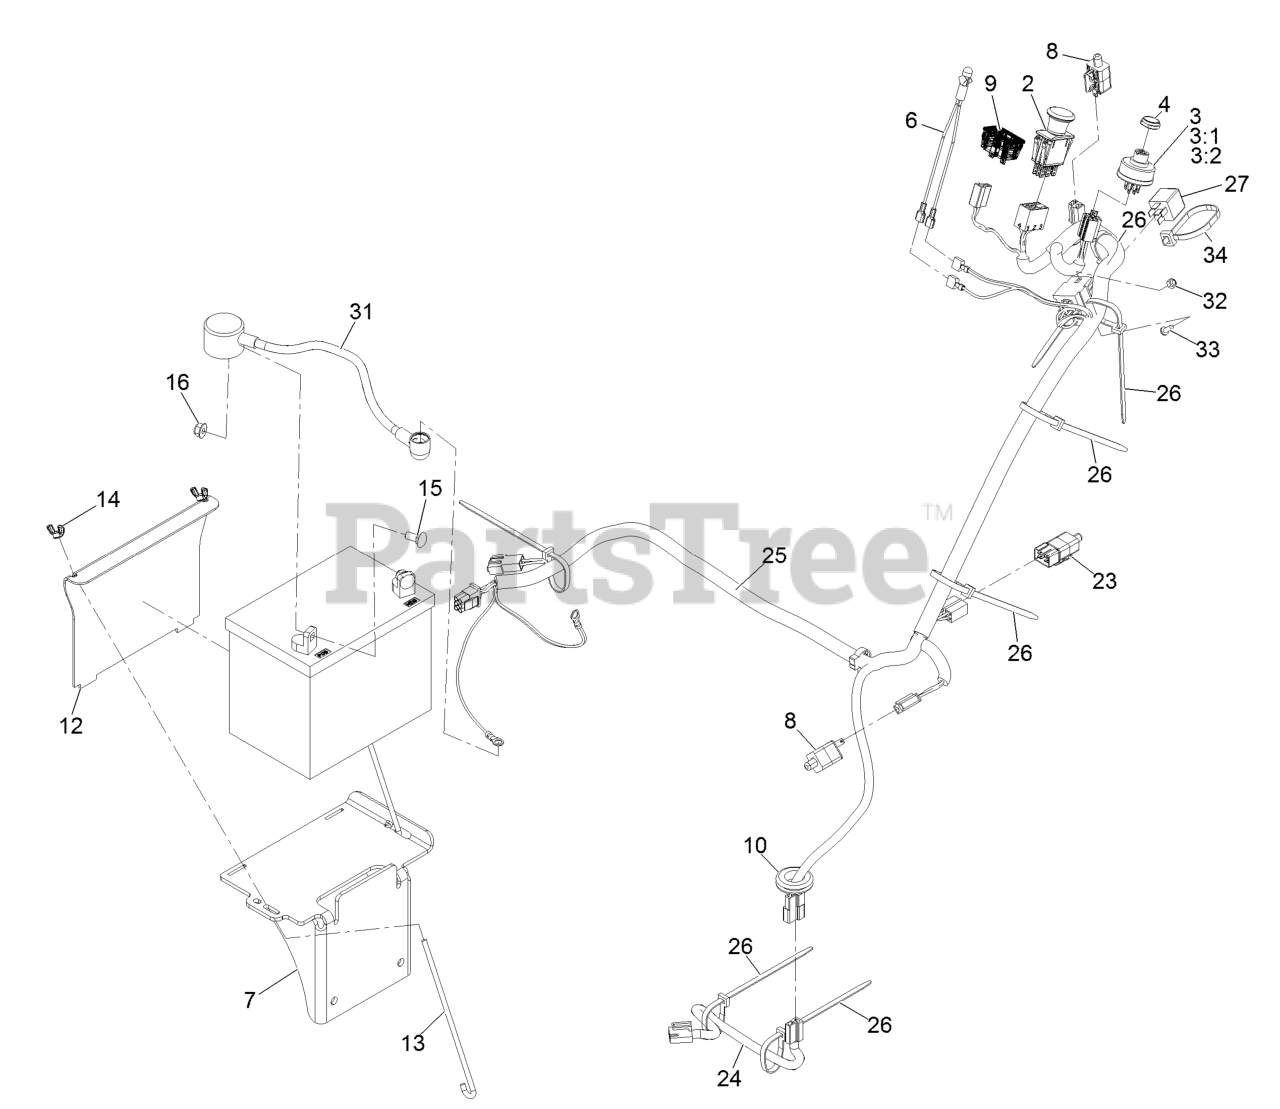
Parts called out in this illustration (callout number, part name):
2	SWITCH-PTO
3:1	WASHER-LOCK
4	NUT-SWITCH, IGNITION
6	INDICATOR-LED, RED
7	WELD, BATTERY MOUNT
9	METER-HOUR
10	GROMMET
12	BRACKET, BATTERY HOLD DOW
13	BOLT-HOLDDOWN
14	WINGNUT
15	BOLT-CARR
16	NUT-HF, NI
23	SWITCH, 2 POLE
24	HARNESS-CLUTCH PIGTAIL
25	HARNESS-MAIN
26	TIE-PLASTIC
31	ASM,POSITIVE BATTERY CABL
32	NUT-LOCK, NI
34	TIE-PLASTIC
